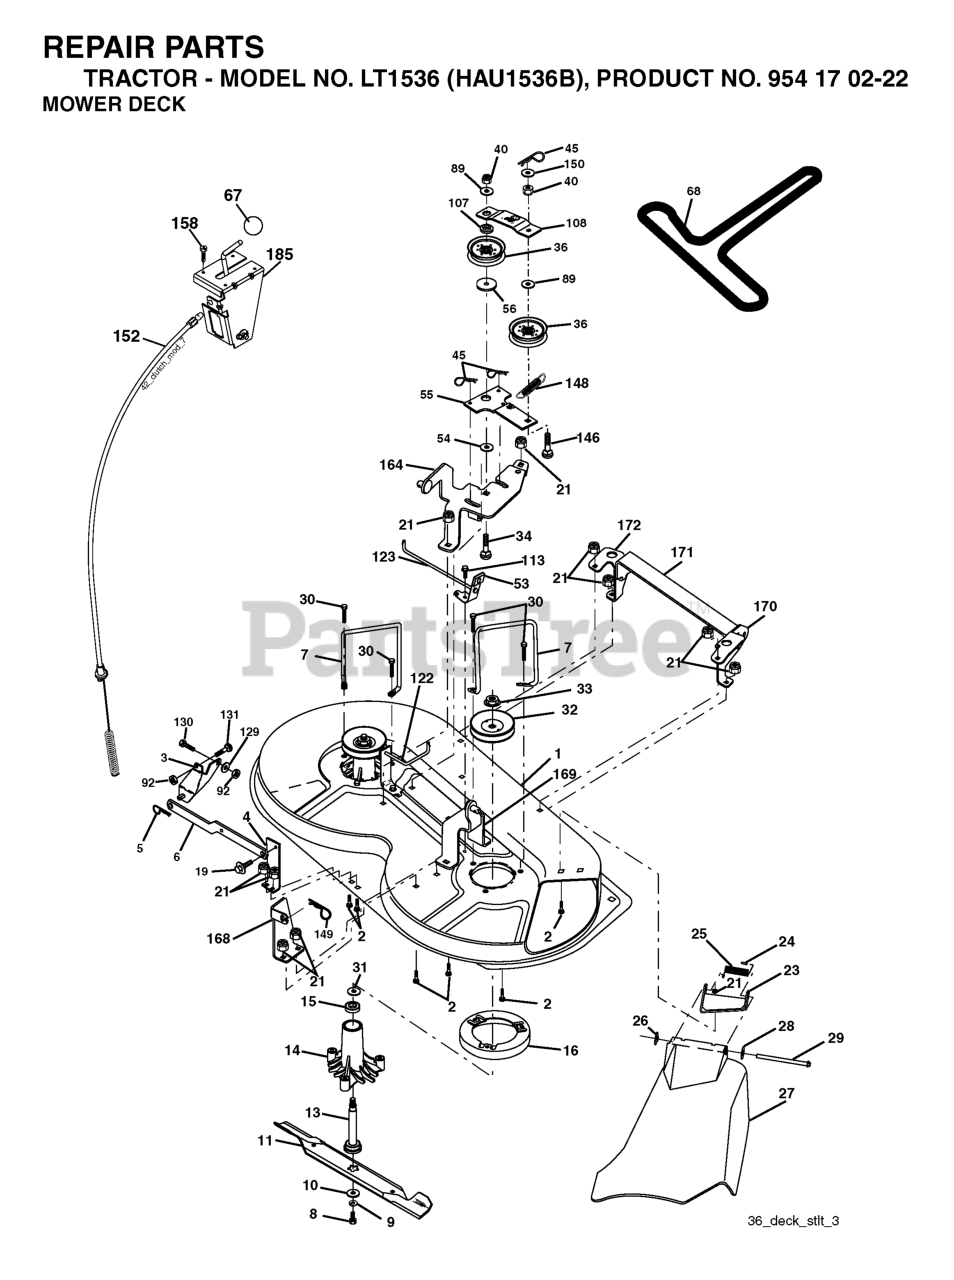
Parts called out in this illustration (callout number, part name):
2	RP BOLT 5/16-18 X3/4 ZN/YEL GR
3	BRKT ASM SWAY BAR
5	RETAINER-SPRNG RB
6	BAR SWAY DECK
8	BLADE BOLT
9	LOCKWASHER
10	WASHER.BLADE
11	BLADE, HI-LIFT 36" PREMIUM
13	SHAFT ASM VENT
14	HOUSING.MANDREL.VENTED (MACHD)
16	STRIPPER.MANDREL.ROUND.BLACK
19	BOLT SHD 5/16-18
21	LOCKNUT
23	BRACKET ASM DEFLECTOR
24	CAP-SLEEVE LT
25	SPRING TORSION
26	NUT PUSH M
27	CONSOLE.STLT.5SP.BLK
28	Washer 11/32 x 5/8 x 16 Ga SD
29	HINGE ROD
30	SCREW, WASHER HEAD
31	WASHER.SPACER.MANDREL
32	PULLEY, MANDREL
33	NUT, FLG TOPLOCK 9/16"
36	FLAT IDLER PULLEY
45	RETAINER M
53	BRAKE ASSEMBLY
55	IDLER ARM
56	SPACER.RETAINER.MOWER
67	KNOB T (3/8 HOLE)
89	WASHER
92	NUT
107	SPACER.IDLER.ARM
108	STIFFENER.IDLER.ARM
113	Screw 5/16-18 x 1/2 Hex, Self Tapping 5/16-18 x 1/2
129	WASHER
130	BOLT
131	BOLT D
146	BOLT, CARRIAGE IDLER
148	IDLER RETURN SPRING
149	SPRING.RETAINER.YELLOW.ZINC
150	WASHER LT
158	SCREW
171	BRACE.SUPT.SUSP.FRT.CRD
185	HEAD ASM. CABLE CLUTCH
